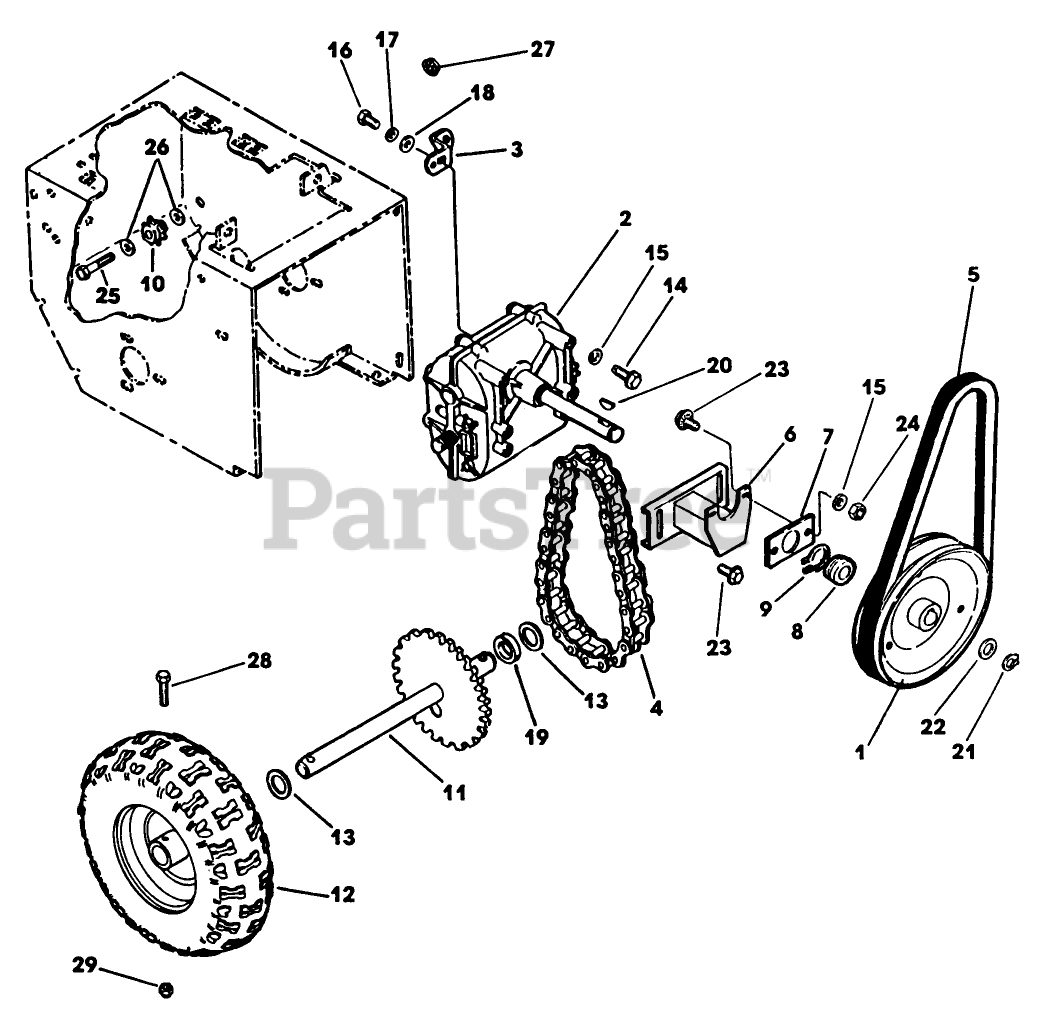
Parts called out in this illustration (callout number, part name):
5	V-BELT
13	WASHER
14	SCREW
22	WASHER-SHIM
24	NUT SS
26	WASHER
29	NUT
